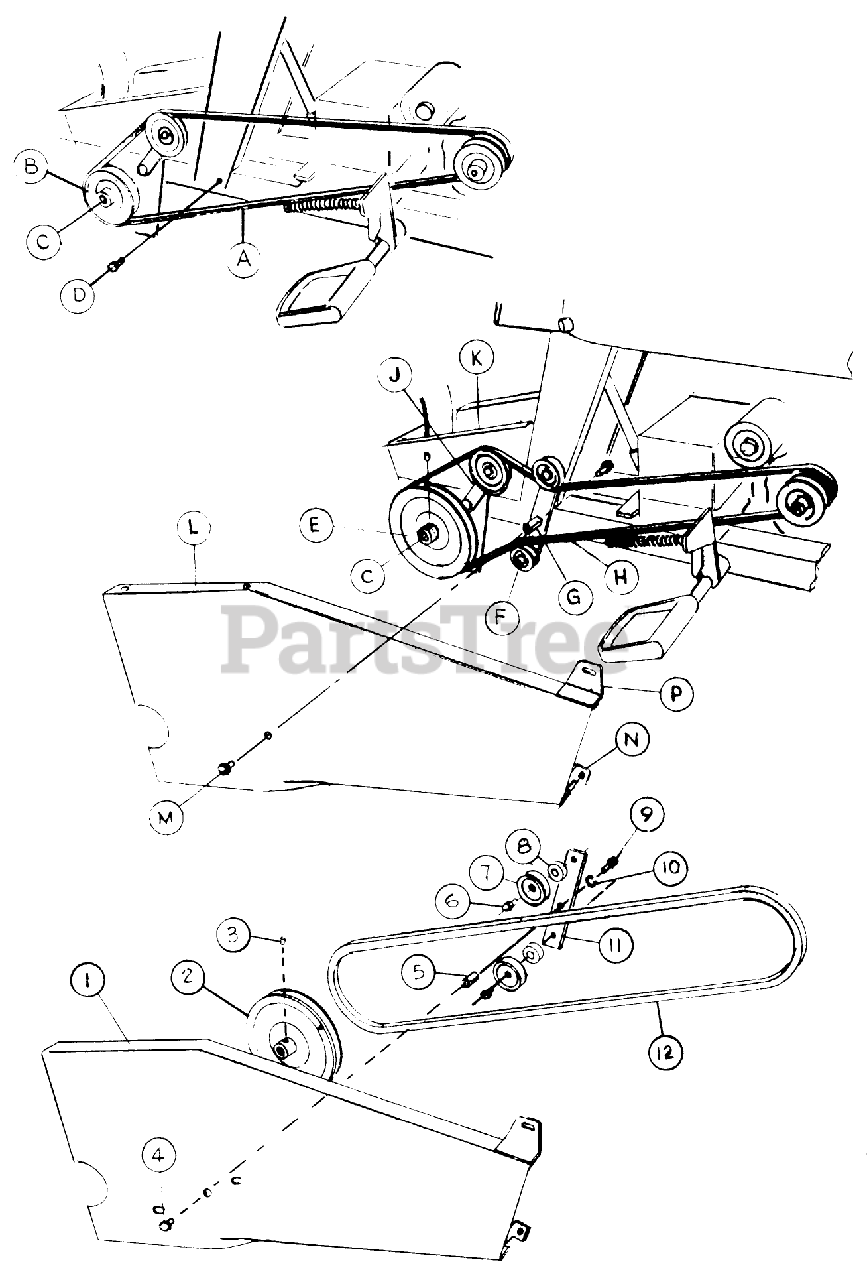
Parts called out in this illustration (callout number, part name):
1	Belt Guard
2	"V" Pulley 7 1/2 O.D.
3	Set Screw 5/16-18 x 5/16
4	Bolt Hex 3/8 16 x 1/2
5	Spacer
6	Bolt 3/8-16 x 1
7	Idler Pulley
8	BUSHING
9	Bolt 3/8-16 x 1
10	Lockwasher
11	Mounting Plate
12	"V" Belt
